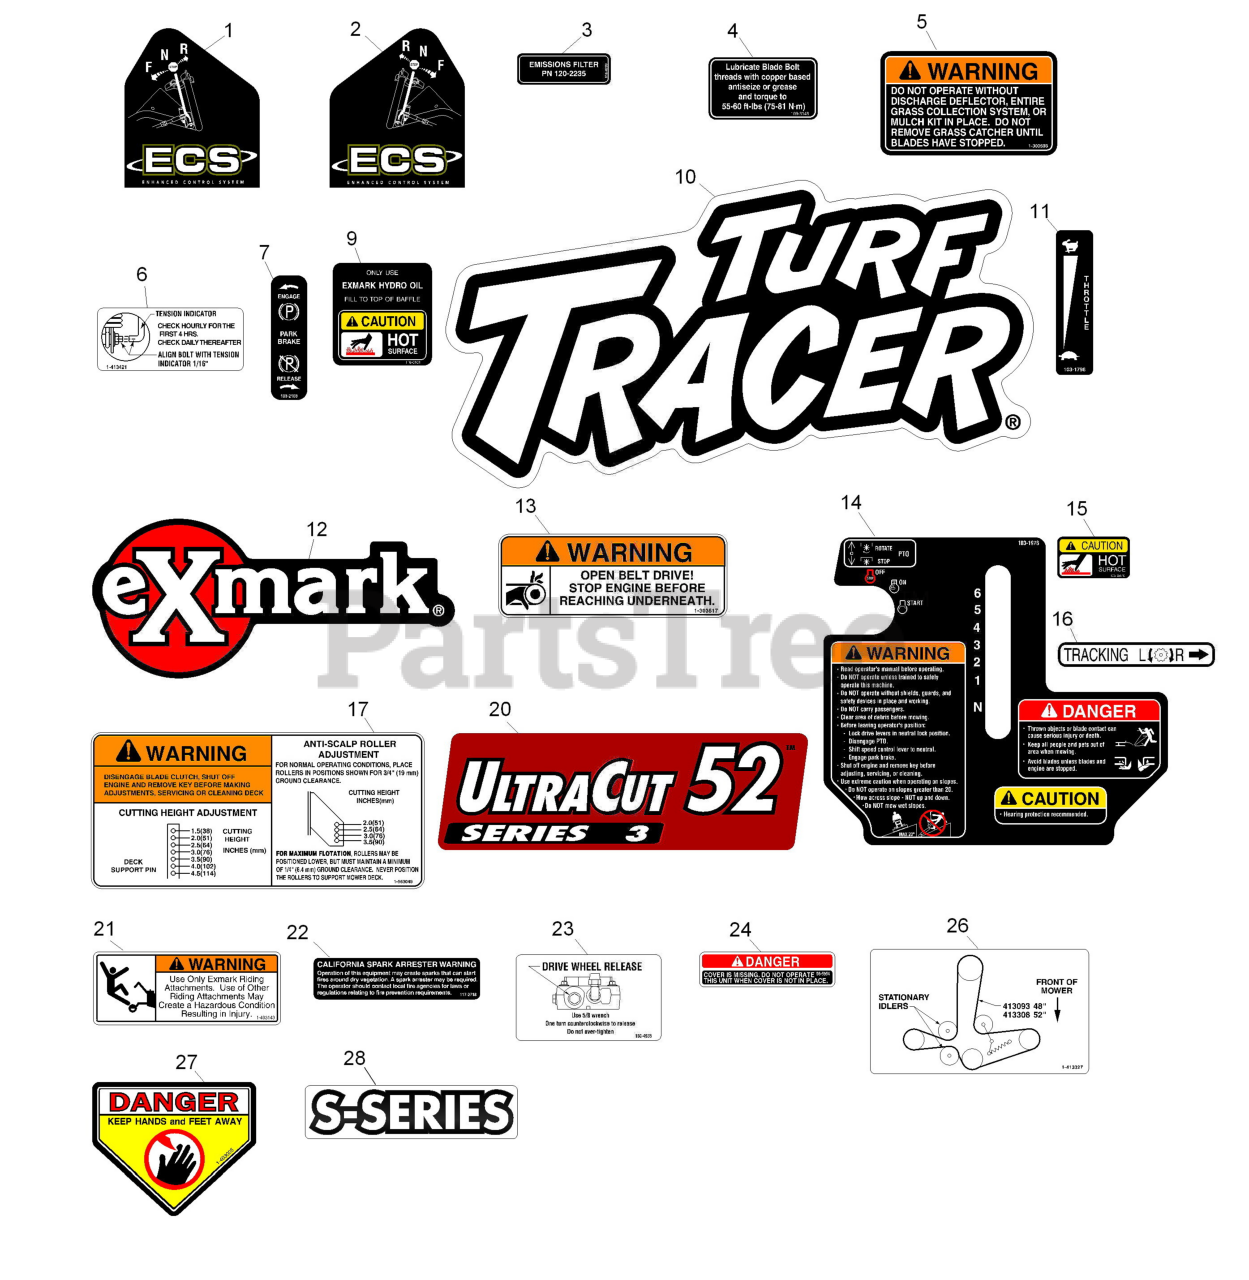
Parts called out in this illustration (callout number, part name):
1	DECAL,LH ECS INSTRUCTION
2	DECAL,RH ECS INSTRUCTION
3	DECAL-FILTER, EMISSIONS
4	DECAL,BOLT TORQUE
5	DECAL-WARNING, DISCHARGE
6	DECAL,INDICATOR
7	DECAL-BRAKE, PARK
9	DECAL-HYDRAULIC TANK
10	DECAL,TTH MODEL
11	DECAL,THROTTLE ONLY
12	DECAL,EXMARK LOGO
13	DECAL,BELT DRIVE
14	DECAL,CONSOLE
15	DECAL-CAUTION
16	DECAL,TRACKING ADJUST
17	DECAL,ANTI SCALP
20	DECAL-ULTRACUT 52 SERIES
21	DECAL,SULKY WARNING
22	DECAL-ARRESTER, SPARK
23	DECAL,DRIVE RELEASE
24	DECAL-COVER, MISSING
26	DECAL,BELT ROUTING
27	DECAL-DANGER
28	DECAL-S-SERIES
